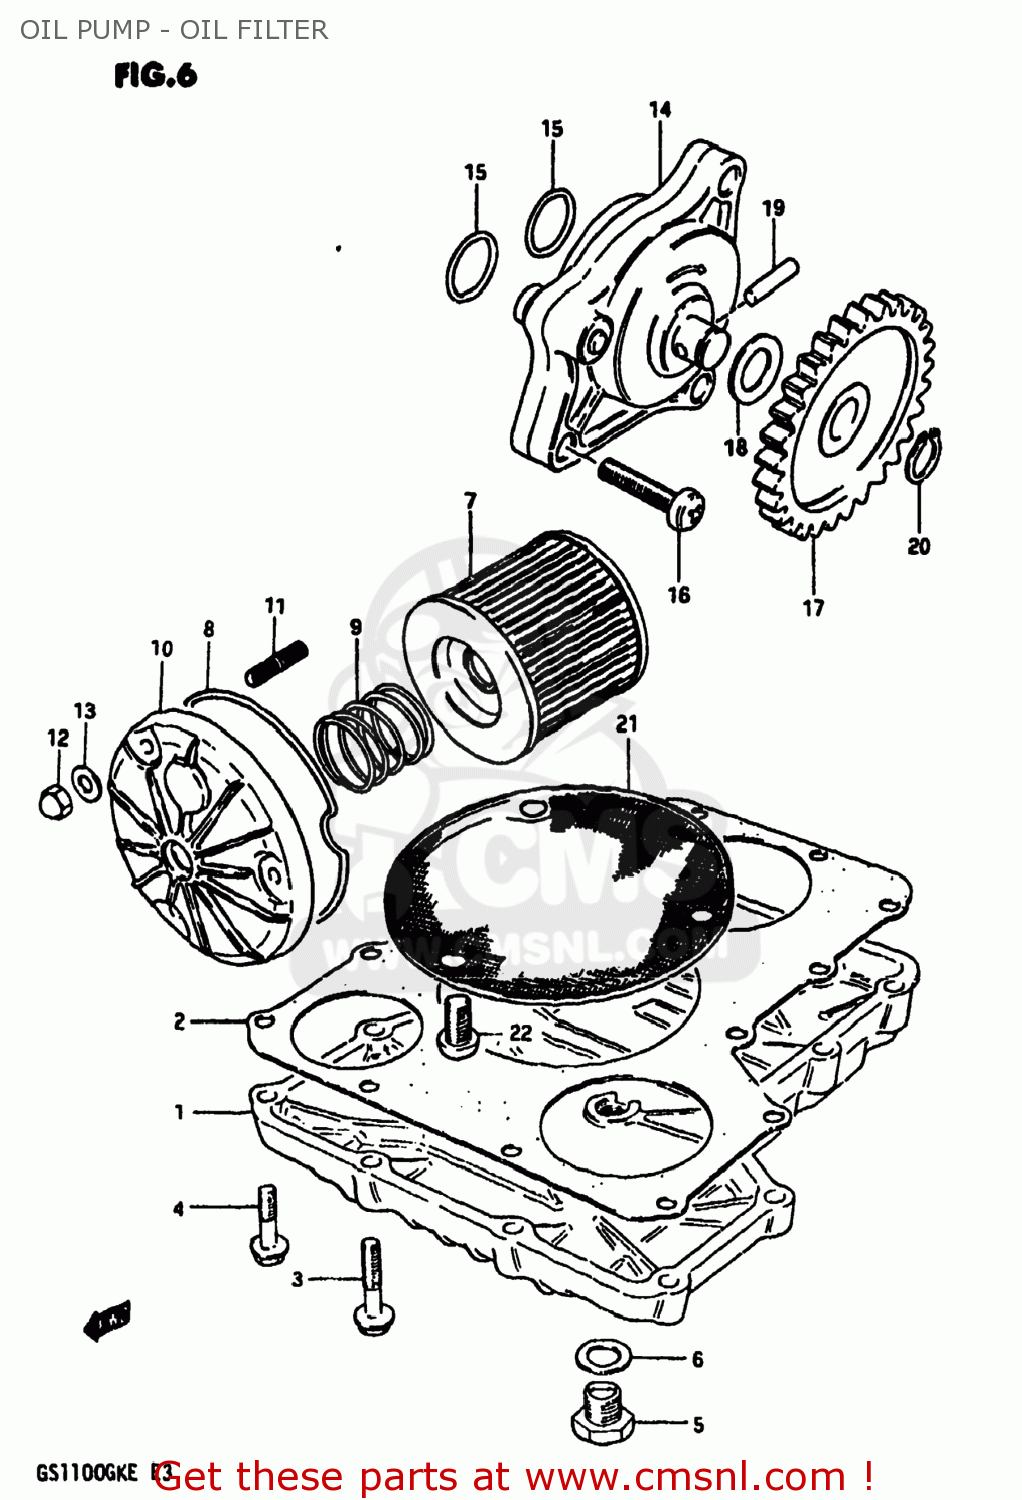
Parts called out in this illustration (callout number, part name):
1	PAN,OIL
2	GASKET,OIL PAN (MCA)
3	BOLT 6X30
4	BOLT
5	PLUG
6	GASKET(14X19.2X2) (NAS)
7	FILTER ASSY,ENGINE OIL
8	O RING,OIL FILTER CHAMBER CAP
9	SPRING
10	CAP,OIL FILTER
11	STUD 6X20
12	NUT 6MM
13	WASHER
14	PUMP ASSEMBLY,ENGINE OIL
15	O RING(D:1.9,ID:13)
16	SCREW
17	GEAR,ENG OIL PUMP DRIVEN(NT:33
18	SHIM
19	PIN(4X15.8)
20	CIRCLIP
21	STRAINER,ENGINE OIL
22	SCREW 6X12
